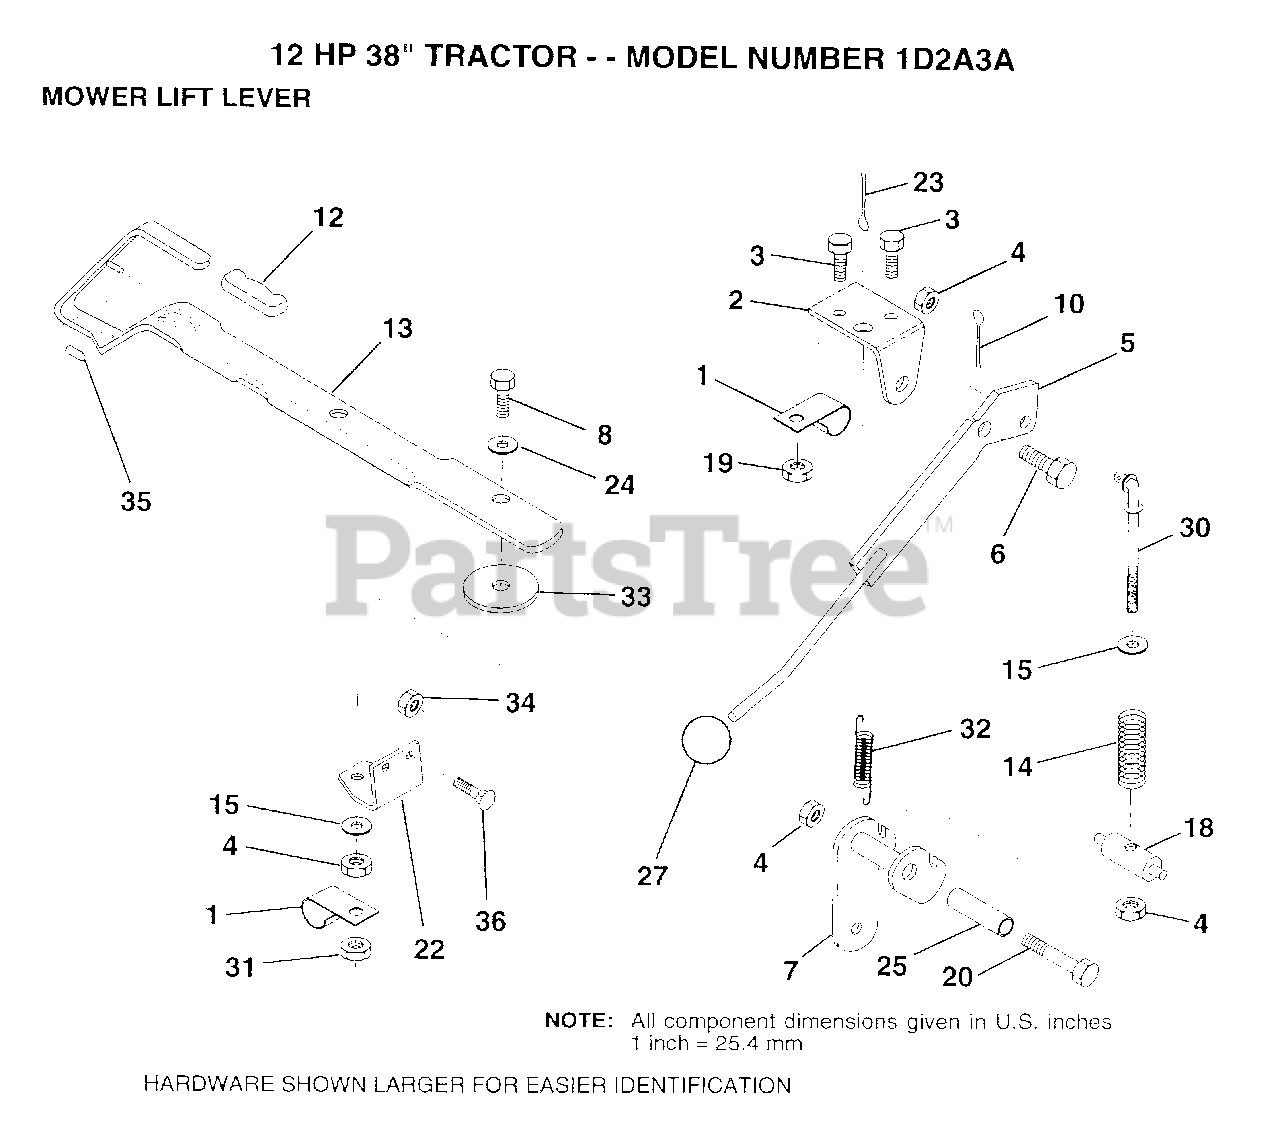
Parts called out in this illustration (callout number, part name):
1	"CLIP,INSULATOR"
2	BRKT CLUTCH
3	BOLT
5	CLUTCH LEVER AS
6	"BOLT, SHOULDER LT"
7	MWR CLUT ARM ASM
8	BOLT
10	COTTER PIN
12	GRIP HANDLE
13	LEVER LIFT LR
14	COMP CLUTCH SPRNG
15	WASHER HYT
18	TRUNNION
20	BOLT
22	LIFT LEVER BRKT
24	WASHER
25	TUBE SPACER
27	KNOB T(3/8 HOLE)
30	ROD TENSION CLUTC
31	LOCKNUT
32	SPRING EXT
33	WASHER
35	VINYL CAP RED
36	BOLT
